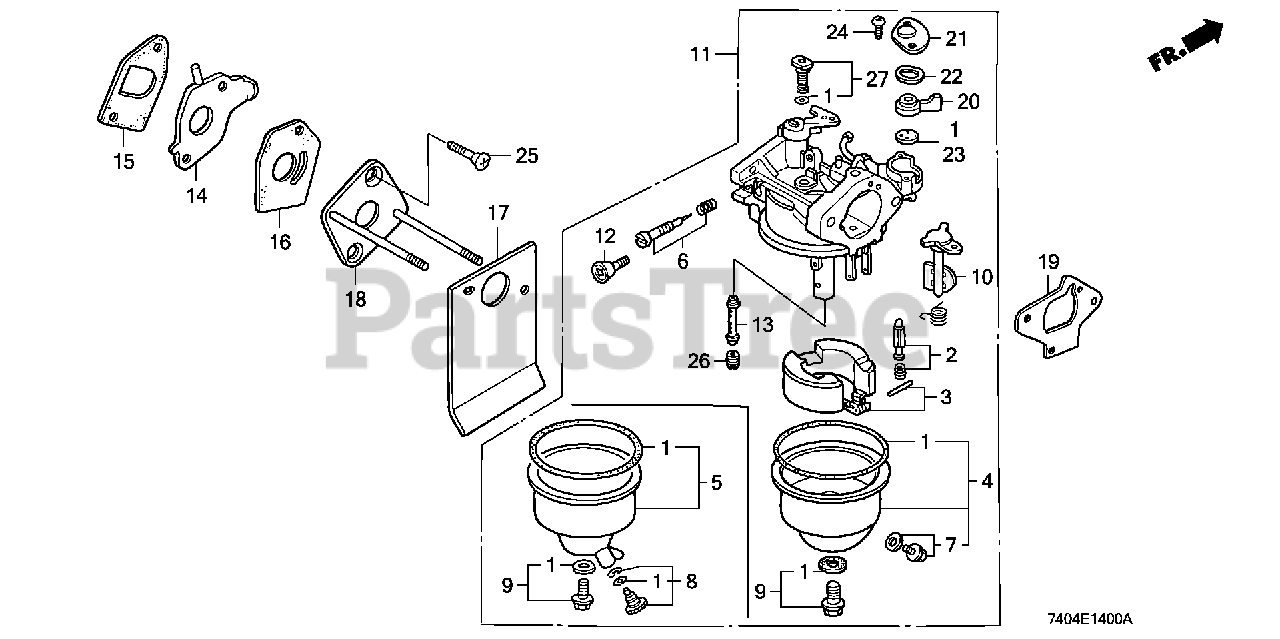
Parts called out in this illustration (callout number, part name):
1	GASKET SET
2	VALVE SET, FLOAT
4	CHAMBER SET, FLOAT
5	CHAMBER SET, FLOAT
6	SCREW SET, PILOT
7	SCREW SET, DRAIN
8	SCREW SET, DRAIN
9	SCREW SET
11	CARBURETOR ASSY.
12	SCREW, THROTTLE STOP
13	NOZZLE, MAIN
14	INSULATOR, CARBURETOR
15	GASKET, INSULATOR
16	GASKET, CARBURETOR
17	GASKET, CARBURETOR
18	PLATE, CARBURETOR JOINT
19	GASKET, AIR CLEANER
20	LEVER, VALVE
21	PLATE, LEVER SETTING
22	SPRING, VALVE LEVER
23	GASKET, VALVE
24	SCREW, PAN (3X8)
25	SCREW, FLAT (3X6)
26	JET, MAIN (#62)
26	JET, MAIN (#58)
26	JET, MAIN (#60)
27	JET SET, PILOT (#35)
